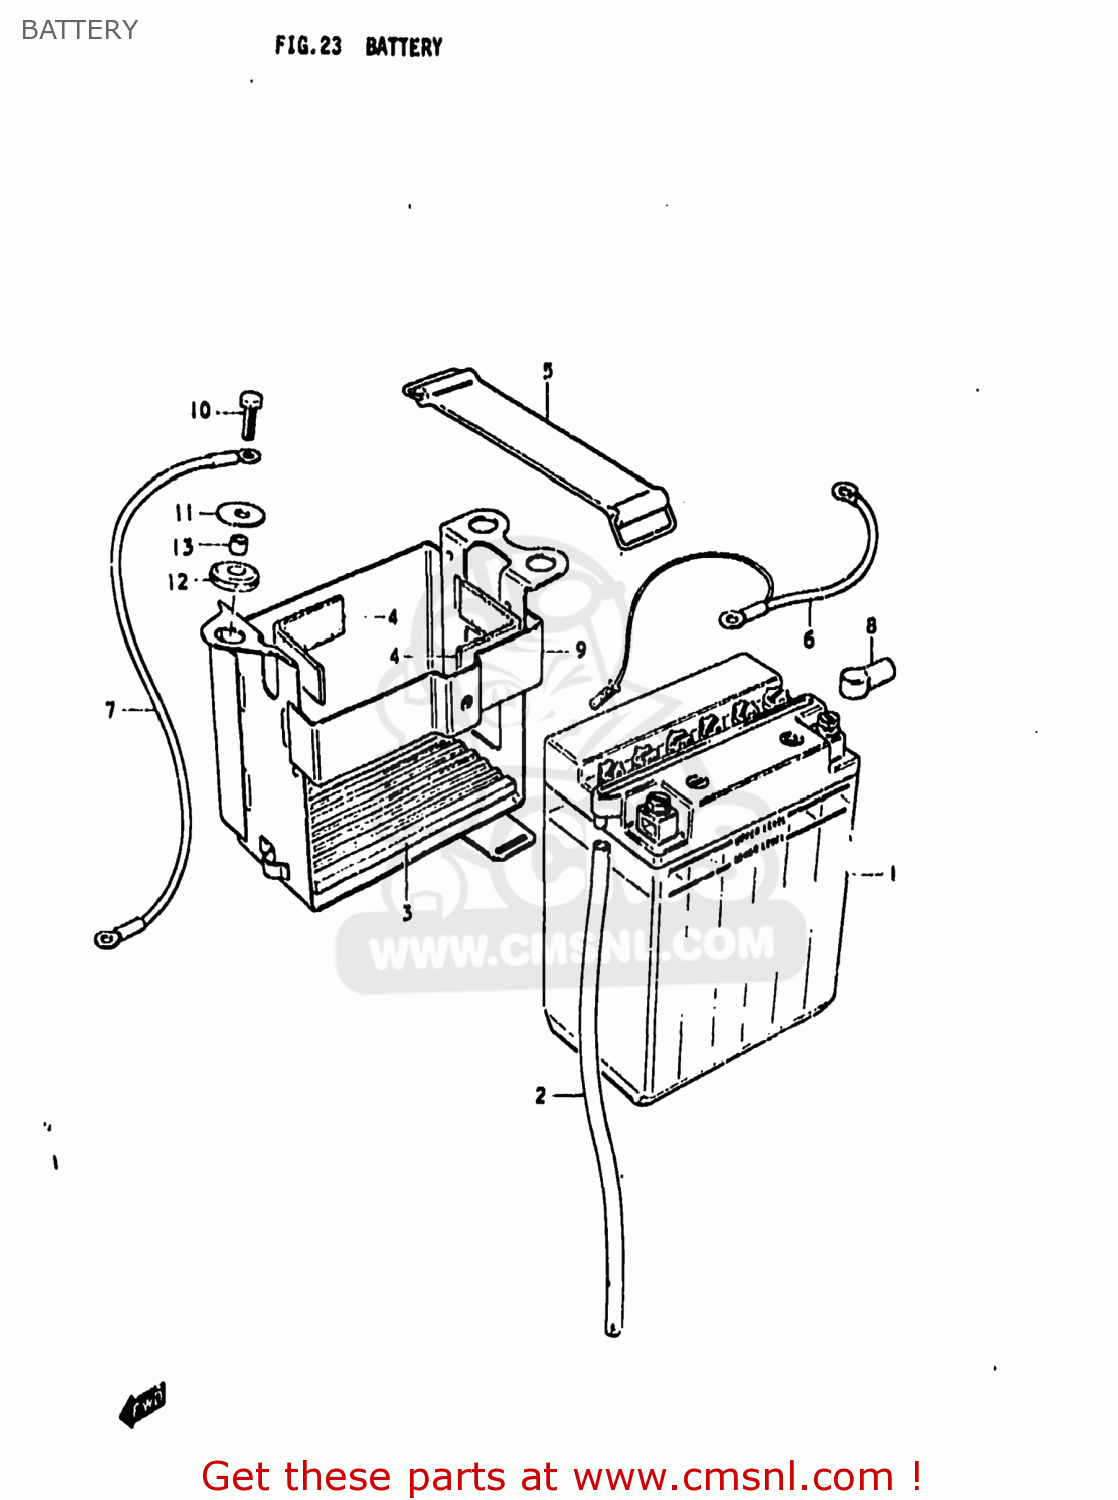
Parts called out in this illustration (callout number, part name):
1	BATTERY ASSEMBLY
2	HOSE,BATTERY EXHAUST
3	PROTECTOR,BATTERY
4	PROTECTOR,20X9
5	BAND
6	WIRE,BATTERY PLUS
7	WIRE,STARTER MOTOR LEAD
8	CAP,TERMINAL
9	HOLDER,BATTERY
10	BOLT, UPPER
11	WASHER(6,5X22X1.6)
12	CUSHION
13	SPACER(6.2X8.3X5.7)
